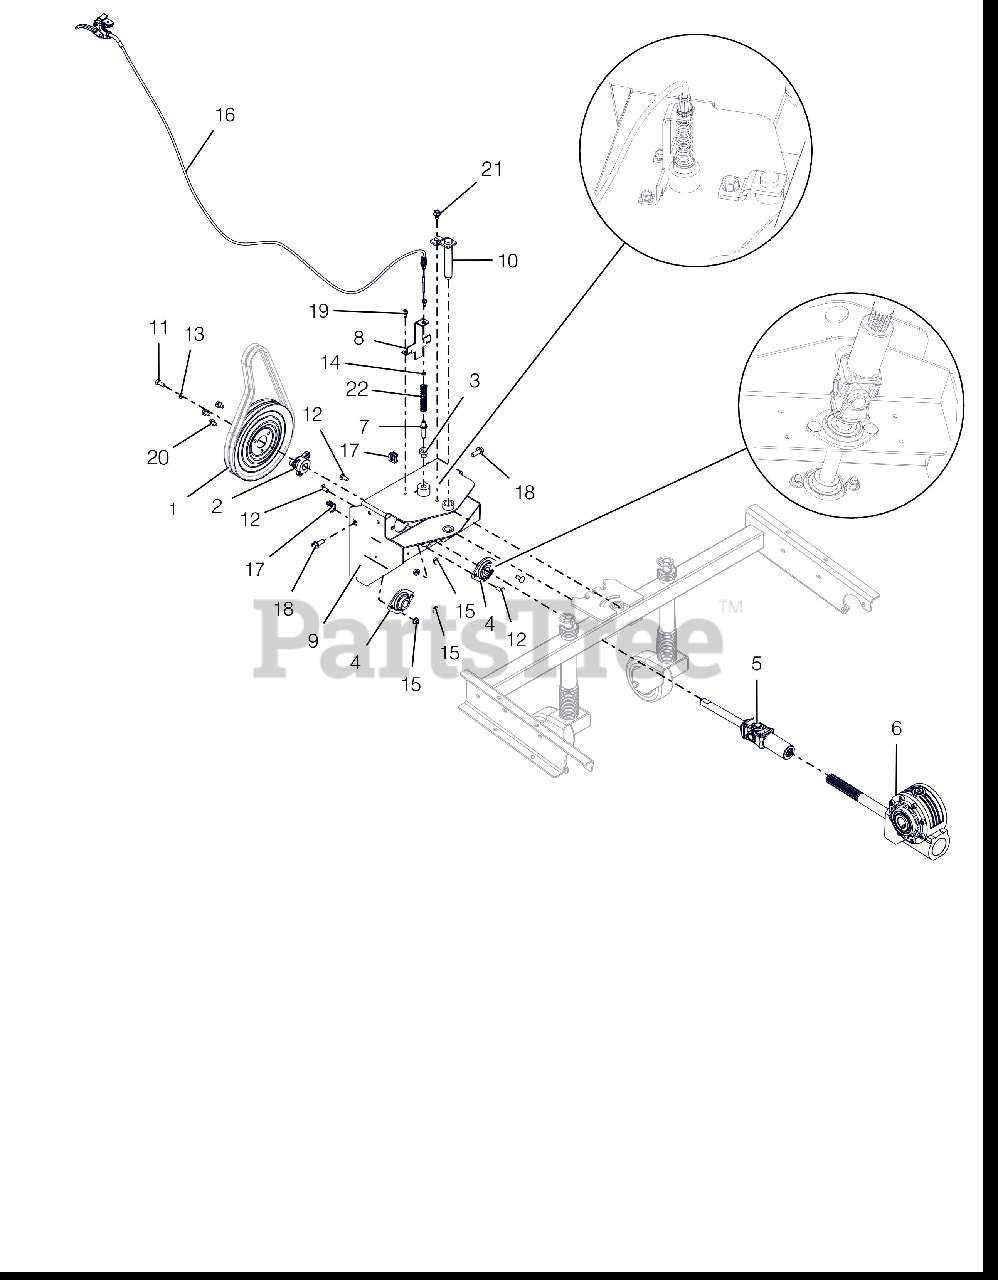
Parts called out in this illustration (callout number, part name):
1	PULLEY, SPIN FORM DUAL GROOVE
2	PULLEY HUB, BOLT-ON D-BORE .75
3	SPACER -FLANGED .390X.500X.781
4	BEARING, 2 BOLT FLANGE -.75 ID
5	DRIVELINE, SERIES 07 (U-JOINT)
6	GEARBOX, WORM - 8.25:1
7	PIN, ADJUSTABLE ANGLE BRUSH
8	BRKT, PIN HOLDER
9	ADAPTER, BRUSH
10	WLDMT, BRUSH PIN
11	BLT-HEX .31-24X.75 YWZC GR5
12	@BLT-RDHDSQNK .31-18X.75 G5YZ
13	WSHR-LK .312X.097 HVY YWZC
14	@NUT-HEX 10-24 YWZC
15	@NUT-LK-TOP-FLG .31-18 YWZC
16	CABLE, REMOTE BRUSH LOCK
17	NUT-RETNR .38-16 TINRMAN
18	BLT-SERHFWH .375-16X1.0 YWZC
19	SCR-TAP .25-20X.50 HWH TR YWZ
20	@SCR-TAP .31-18X.50 HWH TR YWZ
21	@SCR-TAP .38-16X.50 HWH TR YWZ
22	SPRING, COMPRESSION
